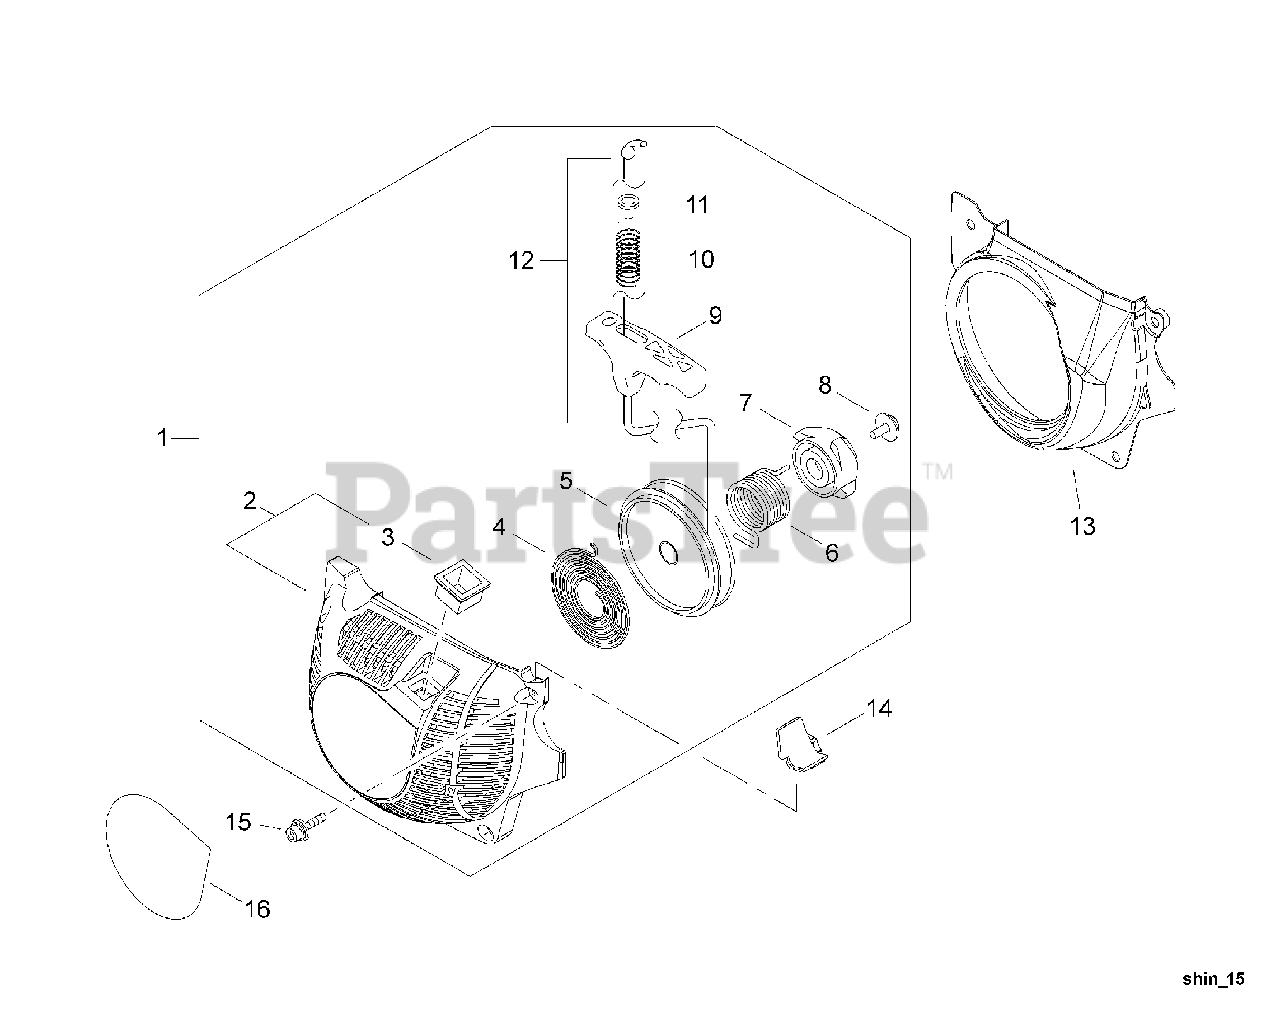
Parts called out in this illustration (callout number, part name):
1	STARTER ASSY
2	STARTER ASSY
3	GUIDE, ROPE
4	SPRING, REWIND
5	REEL, ROPE
6	SPRING
7	CATCHER, PAWL
8	SCREW
9	GRIP, STARTER
10	SPRING
11	COLLAR
12	ROPE, STARTER - 3.8X750
13	CASE, FAN
15	SCREW - 4X16
16	LABEL - MODEL 502s EPA
